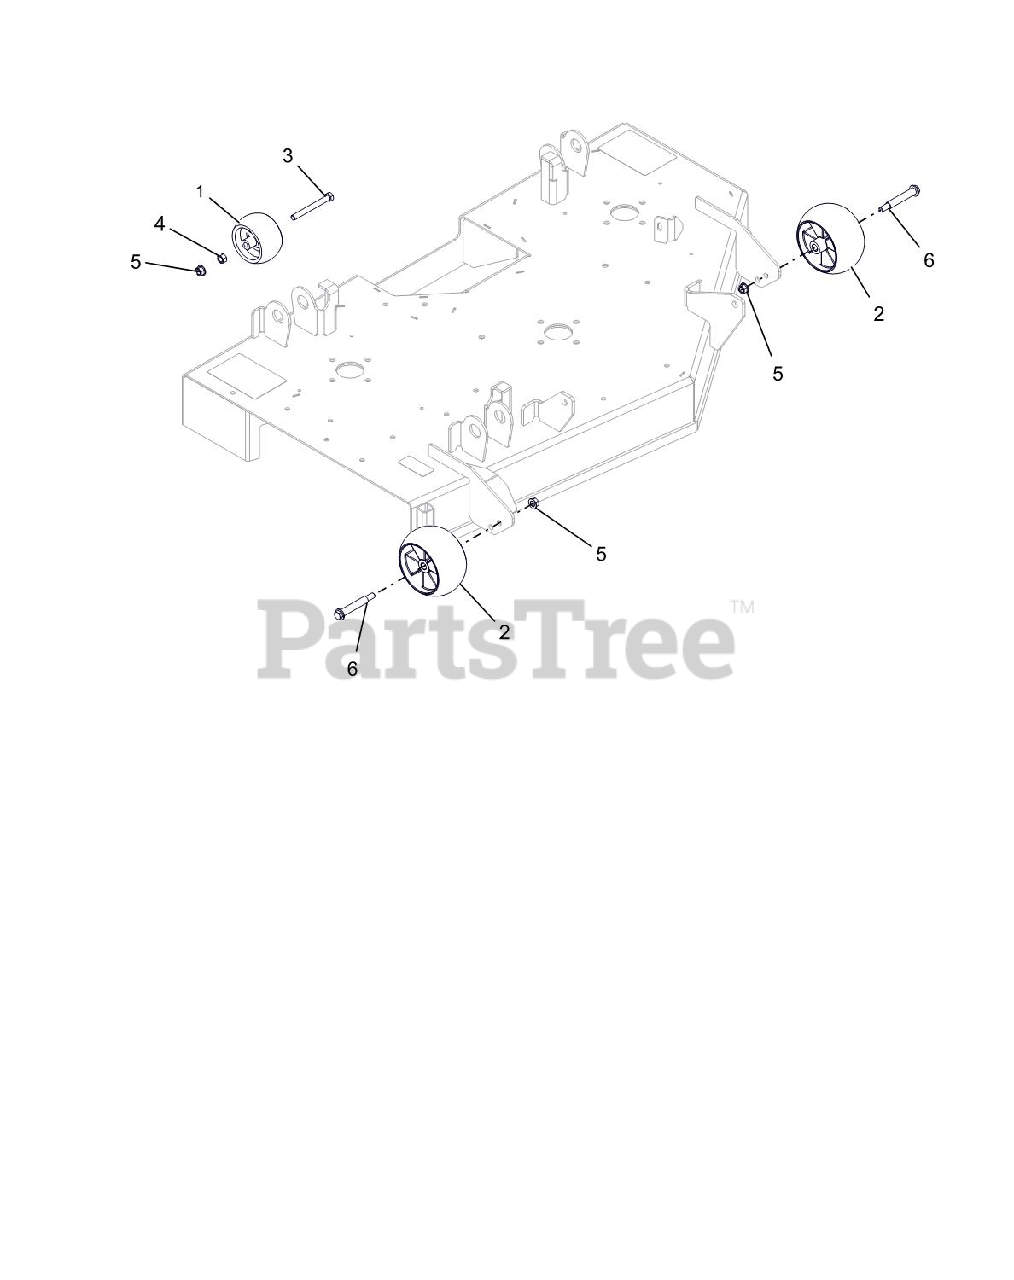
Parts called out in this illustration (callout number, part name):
2	ANTI-SCALP WHEEL - 5X OS
3	@BLT-HEX .38-16X3.50 GR5 YWZC
4	@NUT-HEX .38-16 YWZC
5	@NUT-LK-TOP-FLG .38-16 YWZC
6	BLT-SHLDR .38-16X2.50 HWH G5
